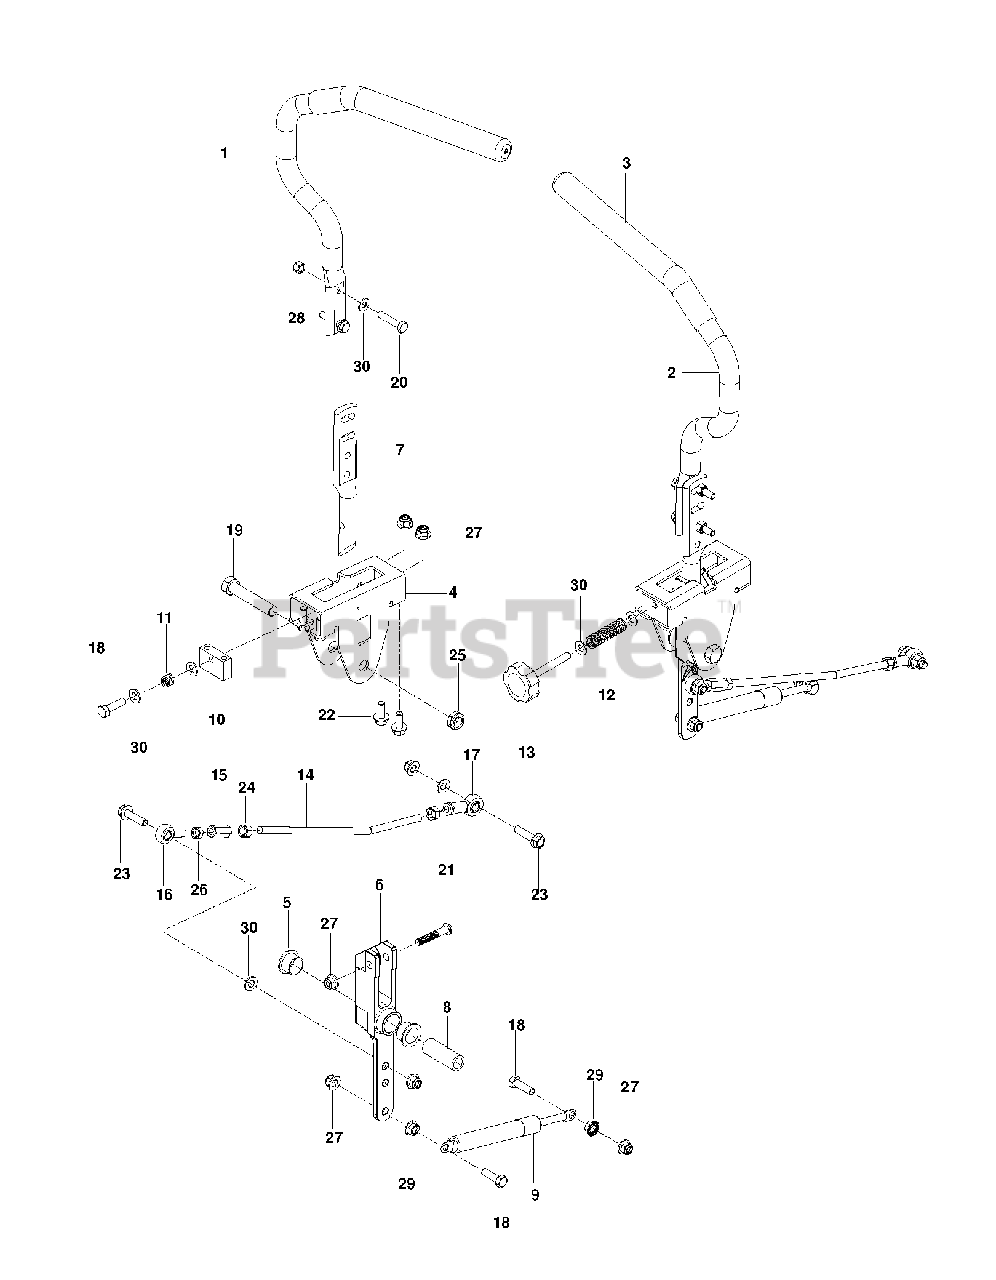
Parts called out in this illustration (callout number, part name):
1	LEVER.DRIVE.W/GRIP.RIGHT
2	LEVER.DRIVE.W/GRIP.LEFT
3	GRIP - DRIVE LEVER 12"
4	BRACKET, CONTROL
5	BEARING, FLANGE
6	LEVER CONTROL PIVOT
7	LEVER.HANDLE MOUNT
8	SPACER, PIVOT CONTROL
10	BLOCK.TRACKING
12	SPRING COMPRESSION 2.0
14	ROD, CONTROL
15	ROD END COUPLER
16	RB ROD.END.LH
17	RH ROD END
18	HCS 5/16C X 1 1/4
19	HCS 1/2C X 2 3/4
20	CAPSCREW 5/16 X 1/1/2 HEX HEAD
21	SCREW 5/16-18 X 1 3/4 BTN-HD
22	HHFS 5/16-18 X 3/4
23	HHFS 5/16-18 X 1.25 TPBLT GD 5
25	NUT 1/2-13 HEX JM NYL
26	NUT 5/16F LEFTHAND
27	5/16-18 NYLOC FLANGE NUT
28	NUT 5/16 NYLOC
29	NUT 5/16C WHIZ
30	FLAT WASHER 5/16 SAE
